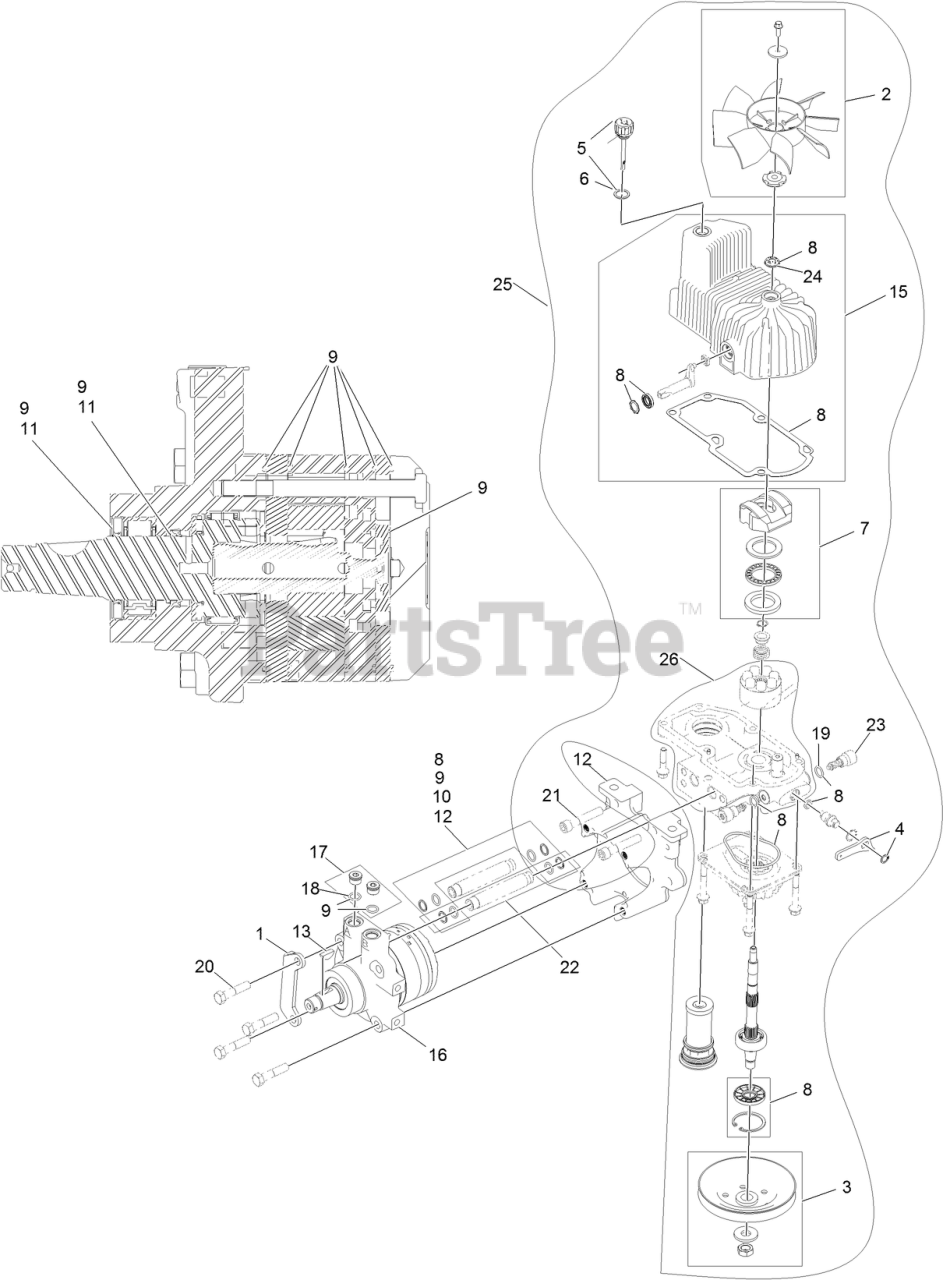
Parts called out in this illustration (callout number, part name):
1	MOUNT-SHOE, HORSE
2	FAN KIT
3	PULLEY KIT
4	HANDLE-BYPASS VALVE, HYDRO
5	DIPSTICK-HYDRO W/GASKET
6	GASKET-DIPSTICK, HYDRO
7	SWASH BLOCK KIT
8	PUMP SEAL KIT
9	MOTOR SEAL KIT
10	TUBE SEAL KIT
11	OUTPUT SHAFT SEAL KIT
12	NOSE CUP-UHT
13	KEY-WOODRUFF
15	HOUSING-HYDRO, RH
16	MOTOR-HYDRAULIC, RH 280CC
17	MAGNETIC PLUGS SERVICE KIT
18	O-RING
19	O-RING-CHECK VALVE
20	SCREW HH
21	SCREW-HSH
22	HYDRAULIC TUBE KIT
23	SHOCK VALVE, 16CC HYDRO
24	SEAL-FAN DRIVE
25	KIT, PUMP SECTION 16CC RH
26	KIT, ROTATING GRP 16CC RH
99	PULLER-PULLEY
